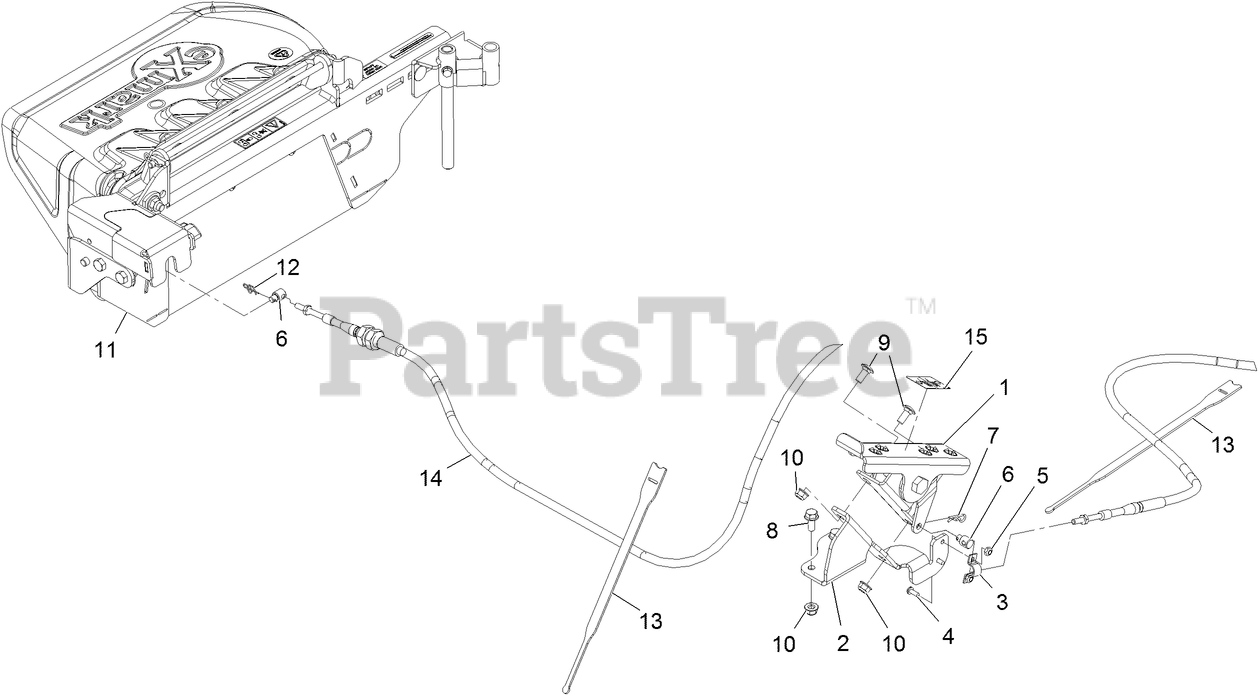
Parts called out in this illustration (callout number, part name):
1	ASM, PEDAL, OCD GATE
2	MOUNT-PEDAL, OCD
4	SCREW-PPH
5	NUT-LOCK, NI
6	PIVOT, CONTROL CABLE
7	PIN-COTTER
8	SCREW-HHF
9	SCREW-CARR
10	NUT-HF, NI
11	ASM, OCD
12	PIN-COTTER, LOCKING
13	STRAP-VELCRO, CABLE TIE
14	CABLE-DISCHARGE GATE
15	DECAL-OCD OPERATION
